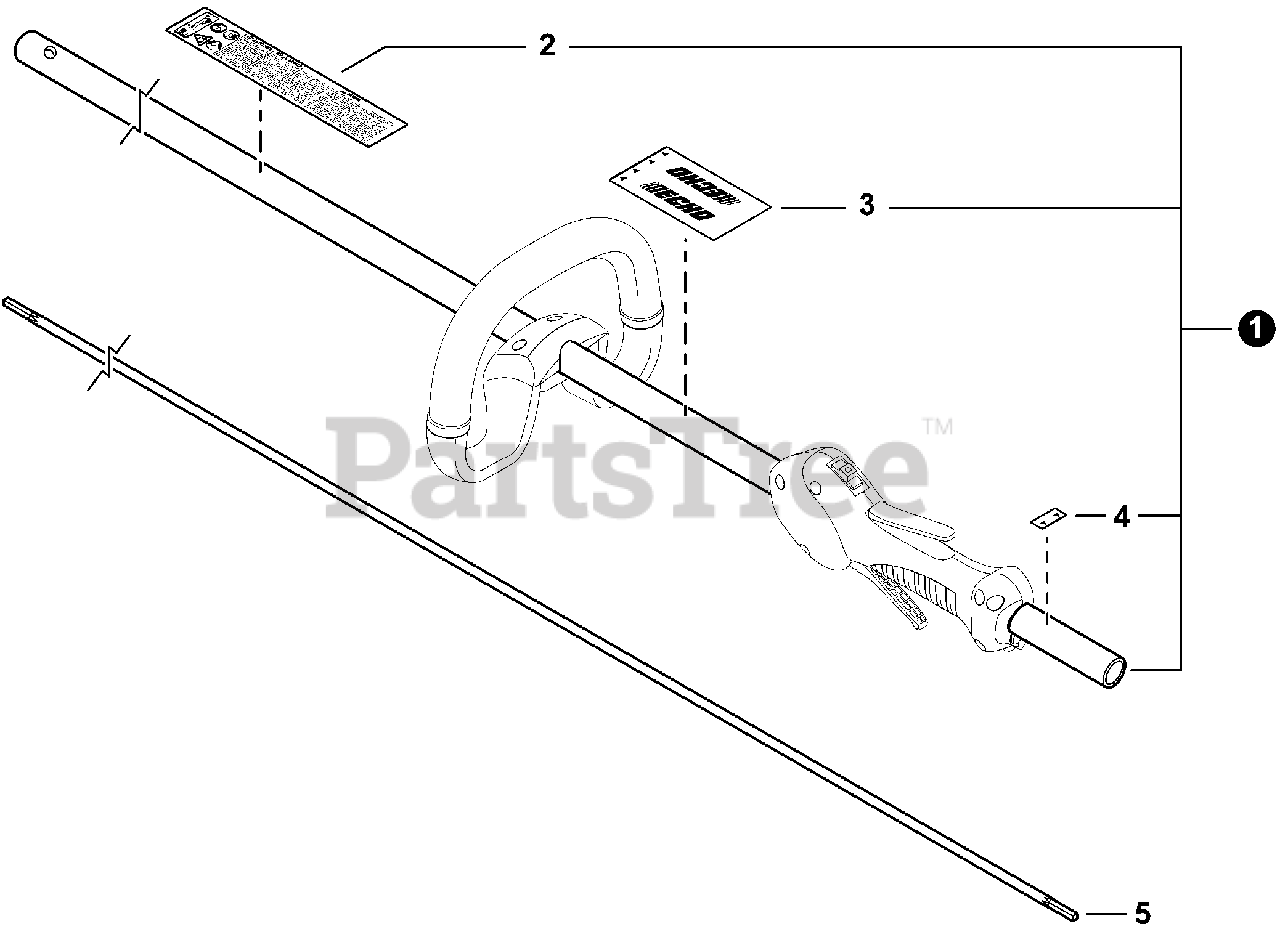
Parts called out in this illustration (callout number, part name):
1	MAIN PIPE ASSY
2	LABEL, CAUTION
3	LABEL, HANDLE LOCATION
4	LABEL - ALIGNMENT
5	DRIVESHAFT
